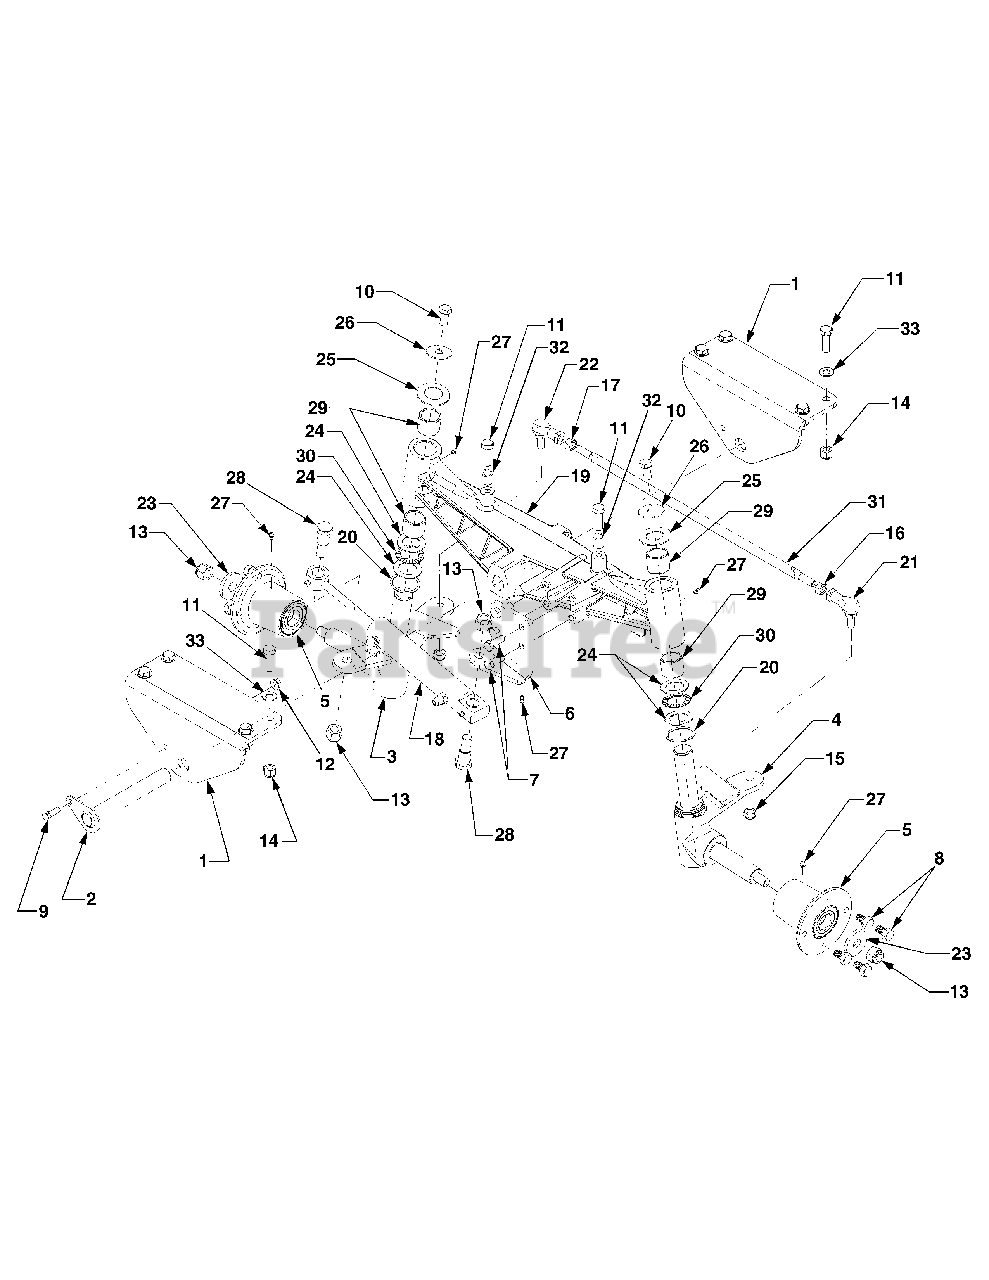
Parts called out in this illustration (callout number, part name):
1	Bracket, Axle Mounting
2	Pin, Pivot Axle
3	Spindle Assembly, Steering LH
4	Spindle Assembly, Steering RH
5	Hub Assembly
8	Bolt, Lug, M12-1.75 x 14 GR8.8
9	Screw, Hex Cap Lock 3/8-16 x 1.0 GR5
10	Screw, Hex Cap Lock 1/2-13 x 1.0 GR5
11	Screw, Hex Cap 1/2-13 x 1.5 GR5
12	Nut, Hx Insert Flnge Lk, 3/8-16 GrF (Replaces 712-3005)
13	Nut, Hex Insert Lock 5/8-11 GR5
14	Nut, Hex Insert Lock, 1/2-13 GR8
15	Nut, Hex Flange Lock, M12 x1.75
16	Nut, Hex, M12 x 1.75 RH Thrd
17	Nut, Hex, M12 x 1.75 LH Thrd
18	Cylinder, Steering
19	Axle, Pivot
20	O-Ring, 1.374 x .139
21	Ball Joint, RH Thrd
22	Ball Joint, LH Thrd
23	Washer, Flat, .66 x 1.94 x .25 ...
24	Washer, Flat, 1.25 x 1.94 x .063
25	Washer, Flat, 1.25 x 2.25 x .040
26	Washer, Flat, .531 x 1.75 x .09
27	Fitting, Lube, 3/6 Drive
28	Screw, Shoulder, .75 x 1.03
29	Bearing, Sleeve, 1.25x1.5x1.25
30	Bearing, Thrust, 1.25 x 1.94 x .78
32	Spacer, .501 x .75 x .775
33	Washer, Flat, .51 x 1.0 x .06
